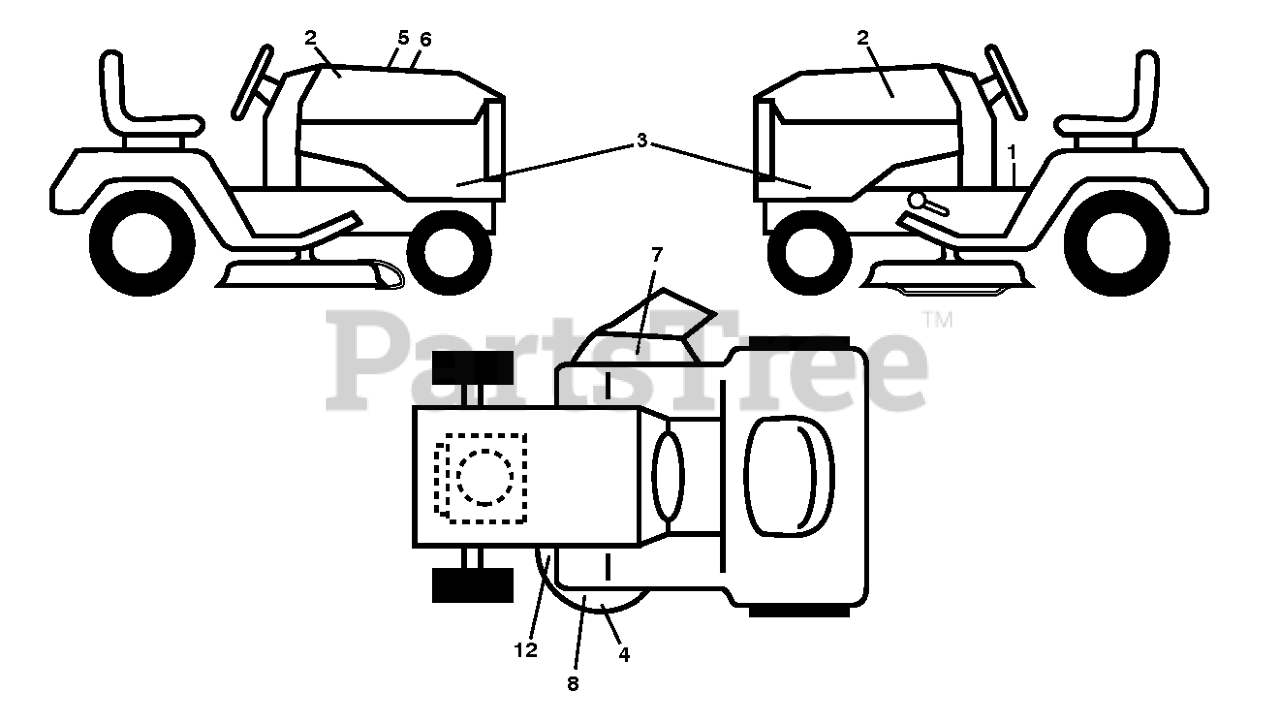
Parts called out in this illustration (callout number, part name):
1	DECAL.FENDER.WARNING.ENGLISH
2	DECAL.WB.178MM.15.HUSQ.NEWBRAN
3	DECAL TRACTOR SIDE PANEL DECAL
4	DECAL.MOWER.CAUTION.TENSION.AR
5	DECAL.WARNING.CUST.RESP.E85.
6	DECAL.RPL.KH.KT7.TLW.48E.K46
7	DECAL, DECK DEFLECTOR, WARNING
12	DECAL.MOWER.SCH.48/54.PREM
